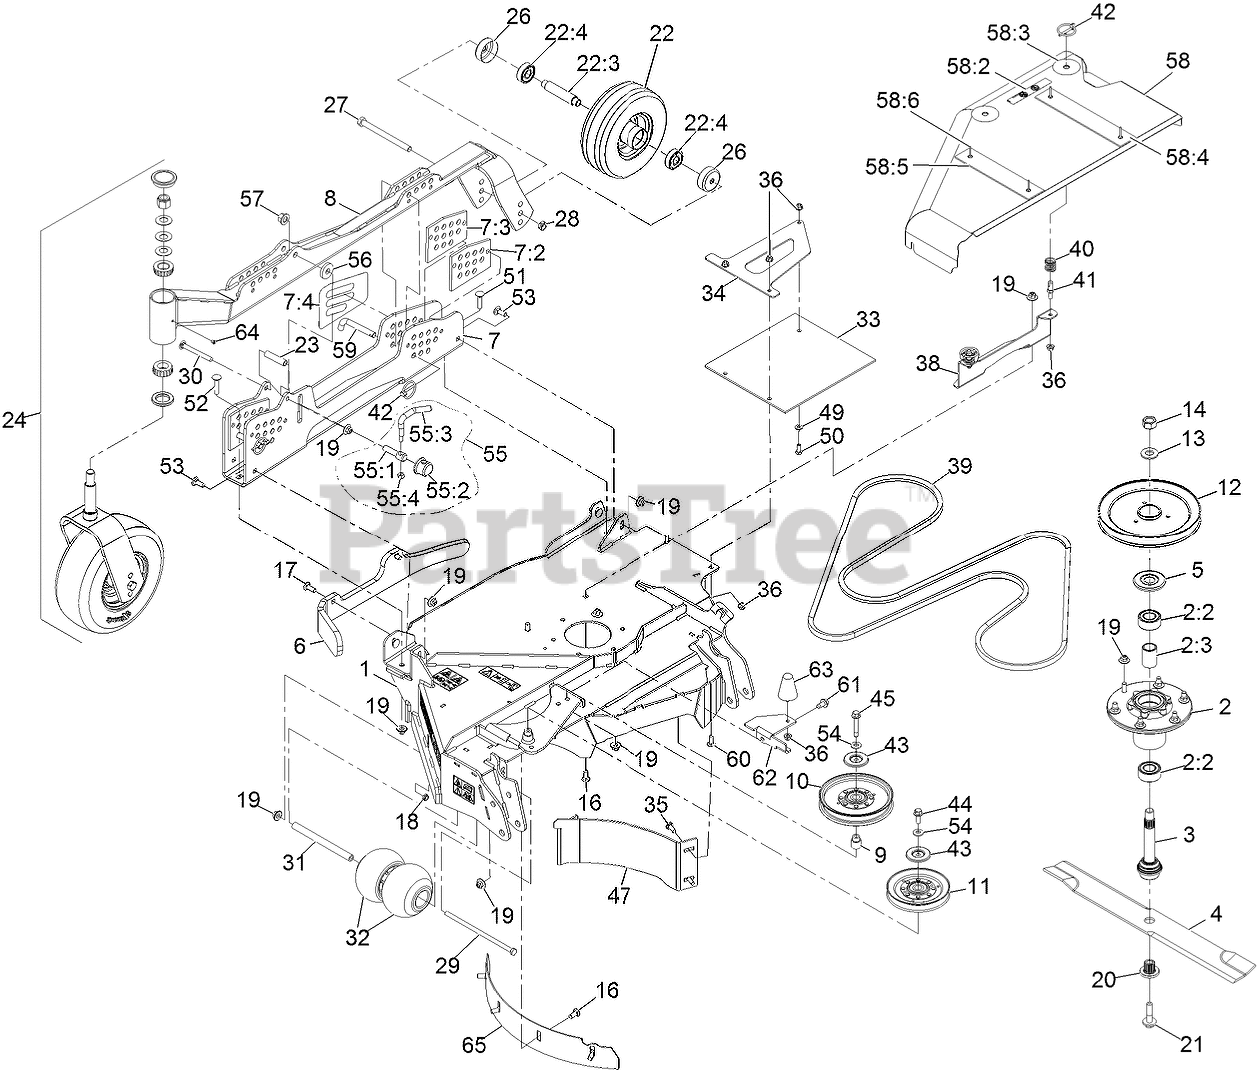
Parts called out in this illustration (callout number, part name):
1	ASM-DECK, RH WING 96
2	ASM-CUTTER HSG
2:2	BEARING-3205 TRASHGUARD
2:3	SPACER-BEARING
3	ASM-SPINDLE AND SEAL
5	GUARD-BEARING, TOP
6	BUMPER-96 RH
7	RH HOC CHANNEL ASM
7:2	PLATE-GUIDE, HOC (LH)
7:3	PLATE-GUIDE, HOC (RH)
7:4	DECAL-HEIGHT OF CUT, RH
8	CALL CUSTOMER SERVICE
9	BUSHING-IDLER
10	IDLER-PULLEY
11	IDLER-V
12	SHEAVE-SINGLE 96RD
14	NUT-HEX
16	BOLT-CARR
17	SCREW-CARR
19	Nut-Nyloc 3/8-16 Flg
20	BUSHING,SPLINED
21	SCREW,SEMS 1/2-20 X 2.19
22	WHEEL AND TIRE ASM
22:3	AXLE-CASTER
22:4	BEARING
26	GUARD, SEAL
27	SCREW-HH
28	NUT-HEX
29	SCREW-HH
30	SCREW-CARR
31	SPACER-WHEEL
32	ROLLER-SCALP, ANTI
33	GUARD-TIRE
34	SUPPORT-FLAP, RH
35	SCREW-CARR
36	NUT-HF, NI
38	BRACKET-SHIELD MOUNT, OUT
41	PIN, SPRING
42	PIN-LYNCH
43	SHIELD-DUST
44	SCREW-HHF 3/8-16 X 1
45	SCREW-HHF
47	BAFFLE-BLOCK, RH WING
49	WASHER-PLAIN
50	SCREW-HH
51	SCREW-CARR
52	SCREW-CARR
53	BOLT-CARR
54	WASHER-BELLEVILLE
55	LEVER ASM
55:1	SCREW-LOCK
55:2	CAP-LOCK
55:4	NUT-LOCK, NI
57	Nut-Lock 1/2-13
58	ASM-Wing Shield RH
58:2	DECAL-NO STEP
58:3	DECAL-SCRATCH COVER
58:4	Plate-Uhmw 2"
58:5	PLATE-FRONT
58:6	Rivet-Pop
59	PIN-HOC
60	BOLT-CARR
61	SCREW-HWH
62	BRACKET-COVER RETAINER
63	BUMPER-RUBBER
65	BAFFLE-DEPTH, RH
